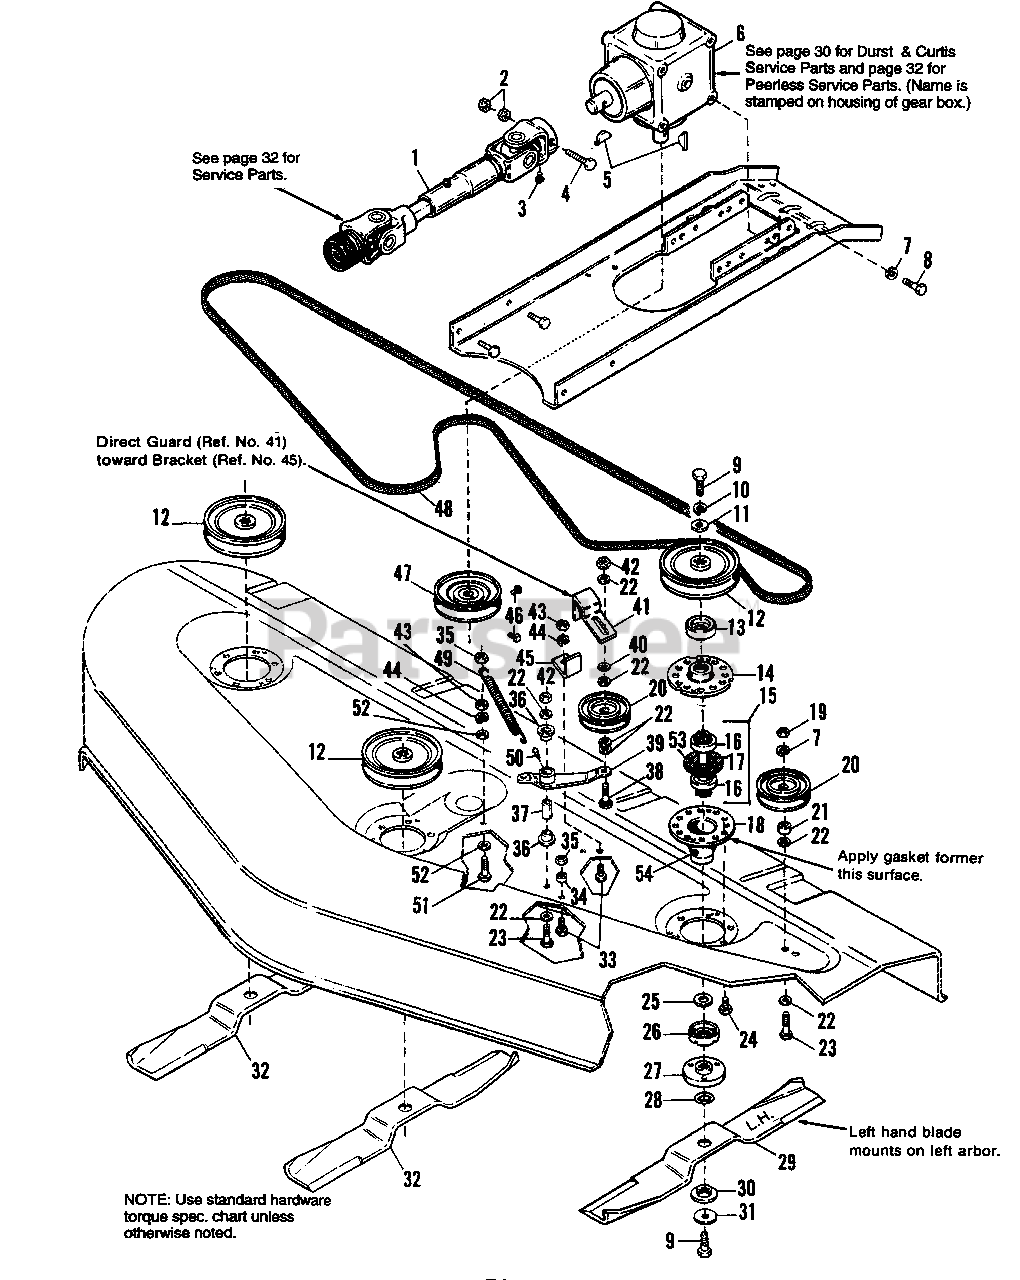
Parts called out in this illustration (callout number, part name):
1	DRIVE SHAFT ASSY., Telescoping
2	LOCKNUT, Hex, 1/4-20
3	SETSCREW, Hex, 5/16-18 x 1/2
4	CAPSCREW, Hex, 1/4-20 x 3
5	KEY, Hi-Pro
6	RIGHT ANGLE GEAR CASE ASSY.
7	LOCKWASHER, 5/8
8	CAPSCREW, Hex, 3/8-16 x 3/4
9	CAPSCREW, Hex, 7/16-14 x 1
10	LOCKWASHER, 7/16
11	WASHER, 7/16
12	PULLEY ASSY., Arbor Drive
13	SHIELD, Bearing Upper, Arbor
14	ARBOR HOUSING, Top
15	ARBOR SHAFT & BEARING ASSY.
16	BEARING
17	SHAFT, Arbor
18	ARBOR HOUSING, Bottom
19	NUT, Hex, 3/8-16
20	PULLEY, Idler
22	WASHER, 13/32
23	CAPSCREW, Hex, 3/8-16 x 1-3/4
24	SCREW, Hex, Taptite, 5/16-18 x 3/4
25	WASHER, Shim
26	SHIELD, Grass
27	ADAPTOR, Blade
28	RING, Self-Locking
29	BLADE, 60" Mower, L.H. Rotation
30	WASHER, Spline
31	WASHER, Spring
32	BLADE, 60" Mower, R.H.
33	CAPSCREW, Hex, 5/16-18 x 3/4
35	LOCKNUT, Hex, 5/16-18
38	CARRIAGE BOLT, Hex, 3/8-16 x 1-1/4
39	LEVER ASSY., Idler
40	LOCKWASHER, Internal, 3/8
42	LOCKNUT, Hex, Jam, 3/8-16
43	NUT, Hex, 5/16-18
44	LOCKWASHER, 5/16
45	BRACKET
46	SETSCREW, Sq. Hd., 5/16-1/2
47	PULLEY ASSY., Drive
48	BELT, Arbor Drive
50	FITTING, Lube, 90
51	CAPSCREW, Hex, 5/16-18 x 1-3/4
52	WASHER, 11/32
53	GASKET, Foam
54	GREASE FITTING
